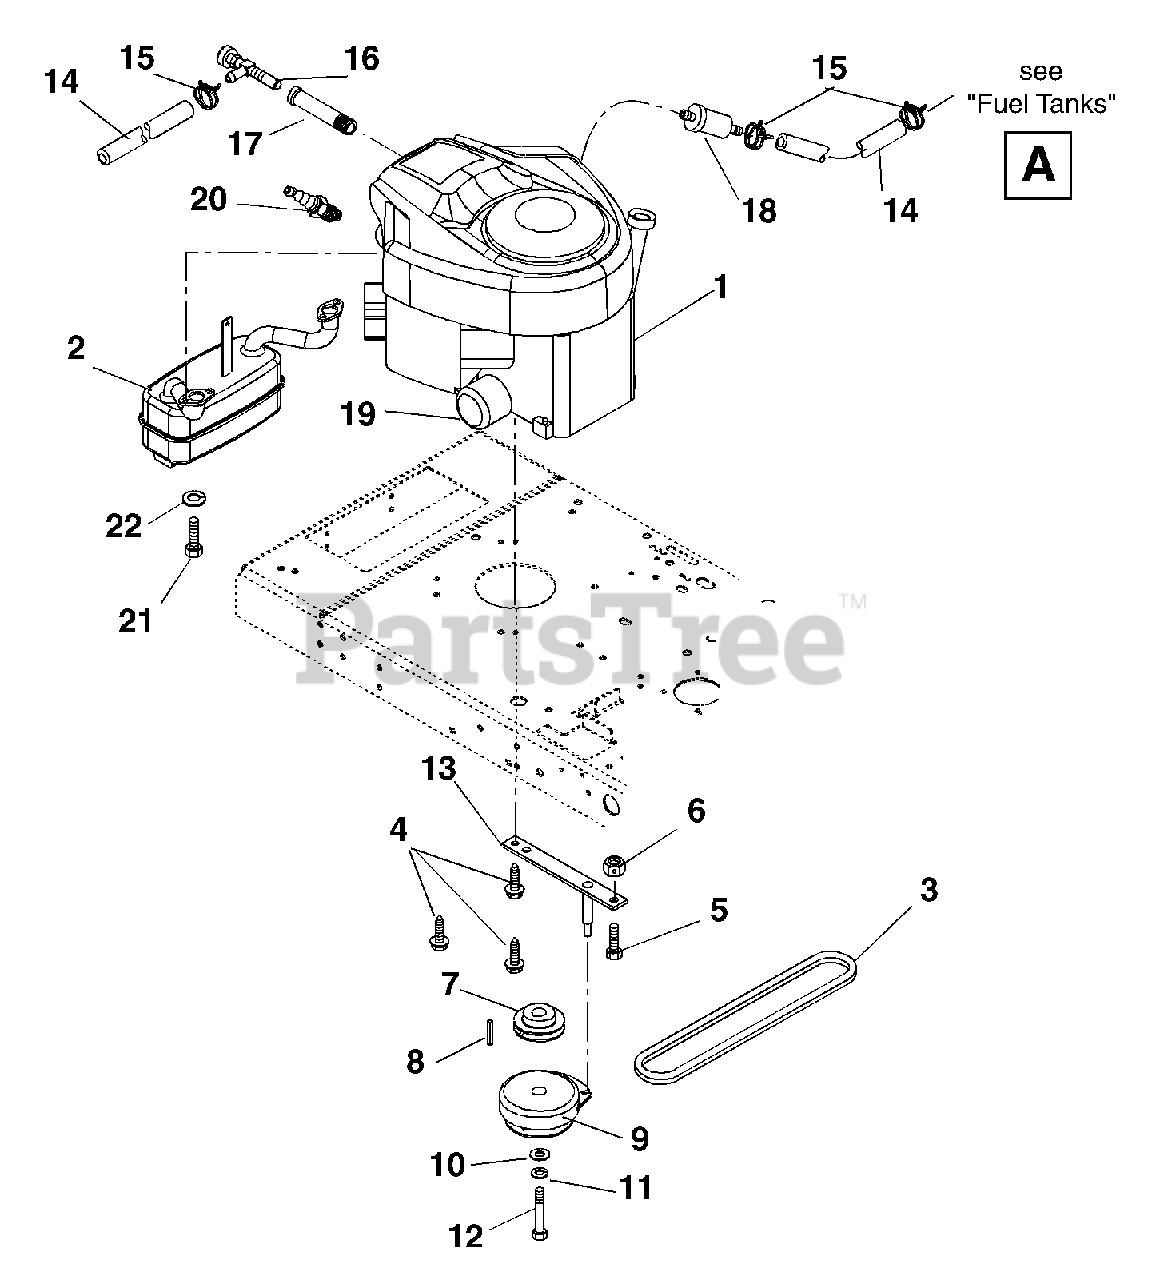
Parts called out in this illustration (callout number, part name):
1	Engine, 20 HP Briggs & Stratton Intek 6-Pin
2	Muffler Assembly
3	V-Belt HA-Section 73.50 x .531
4	Screw-Tapping Hex-Washer-Head .38-16 x 1.25
5	Bolt-Hex .31-18 x 1.75 Grade 5
6	Nut-Locking-Center .31-18
7	Pulley-4.46 Dia. x 1.12 Bore
8	Key-Square .25 x 1.00 x .25
9	Clutch, Electric
10	Washer-Flat-Steel .515 x 1.625 x .250
11	Washer-Locking .44 x .109
12	Bolt-Hex .44-20 x 3.00 Grade 5
13	Anchor-Clutch
14	Gas Line-Bulk .25" I.D.
15	Hose-Clamp
16	Cock-Oil Drain
17	Adapter-Oil Drain
18	Fuel Filter
19	Oil Filter
20	Plug, Spark
21	Screw-Socket Head M8 x 1.25 x 20
22	Washer-Locking .31 x .078 Regular
